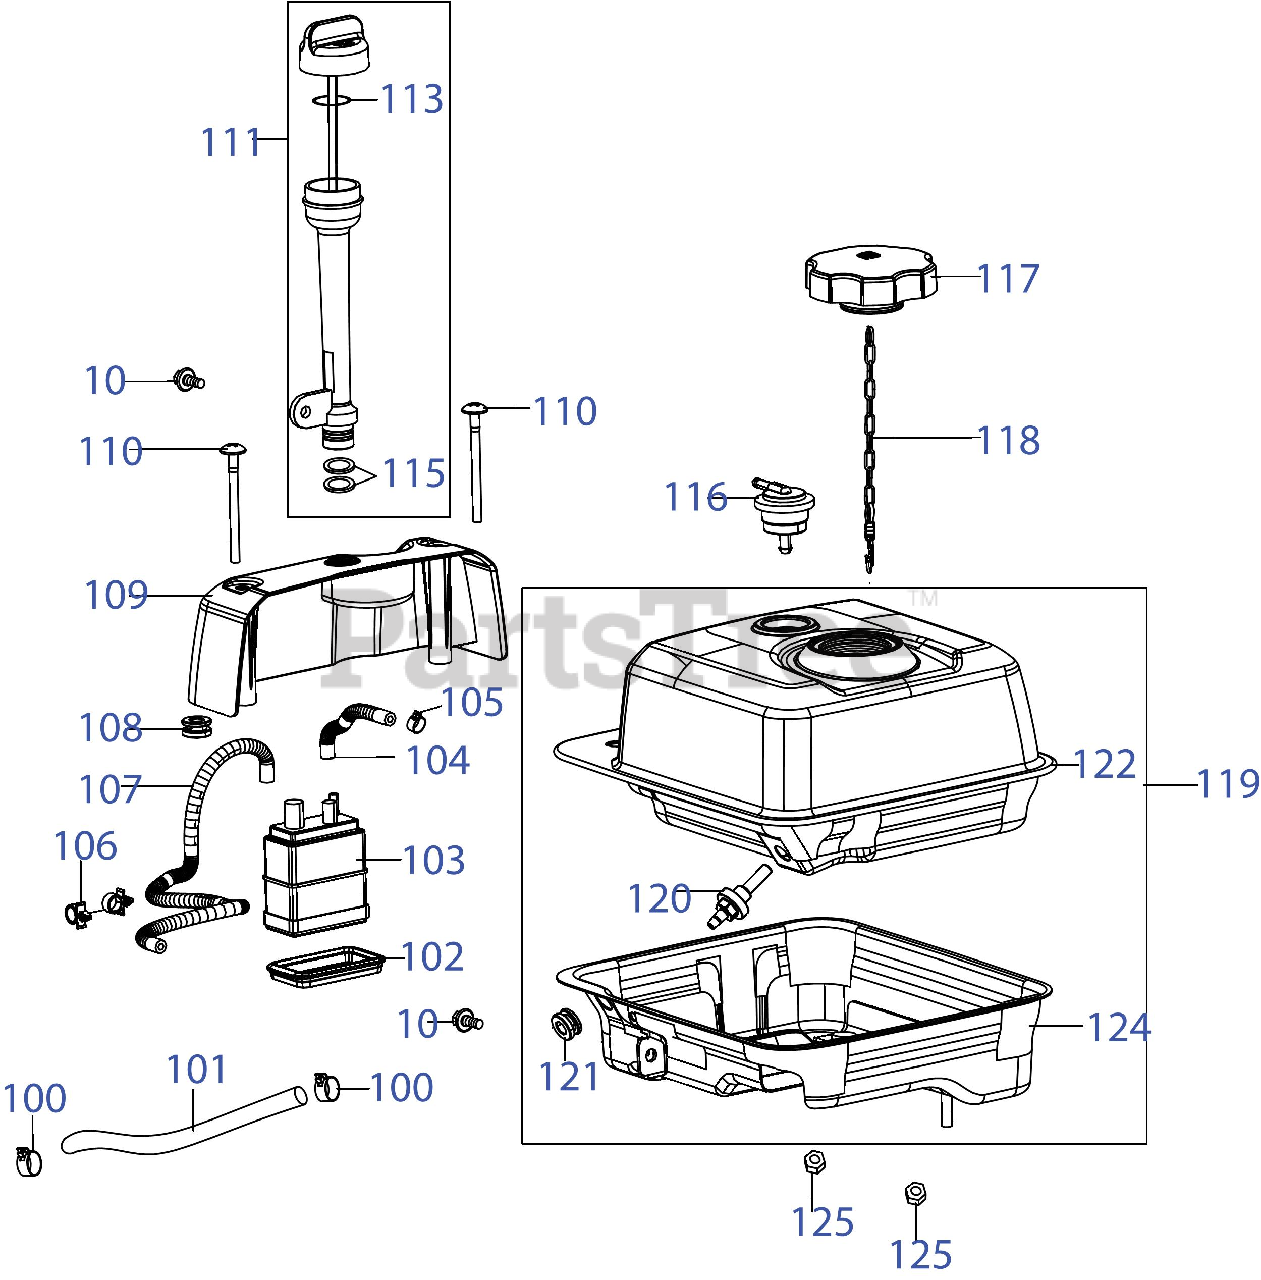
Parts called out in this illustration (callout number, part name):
10	Bolt M6x12
100	Clamp, Fuel Hose
101	Fuel Hose 6.3x12.5x123
102	Gasket, Carbon Canister
103	Carbon Canister
104	Fuel Hose 4x8x108
105	Clamp, Fuel Hose
106	Wire Clamp
107	Fuel Hose
108	Vibration Pad
109	Decoration Cover, Dipstick
110	Panel Bolt
111	Dipstick Assembly
113	O-Ring 21x2.77
115	O-Ring 15.5x1.5
116	Roll Over Valve
117	Fuel Cap
118	Fuel Cap Chain
119	Fuel Tank
120	Drain Pipe
121	Vibration Pad
122	Fuel Tank
124	Tank Base Combination
125	Flange Nut M6
